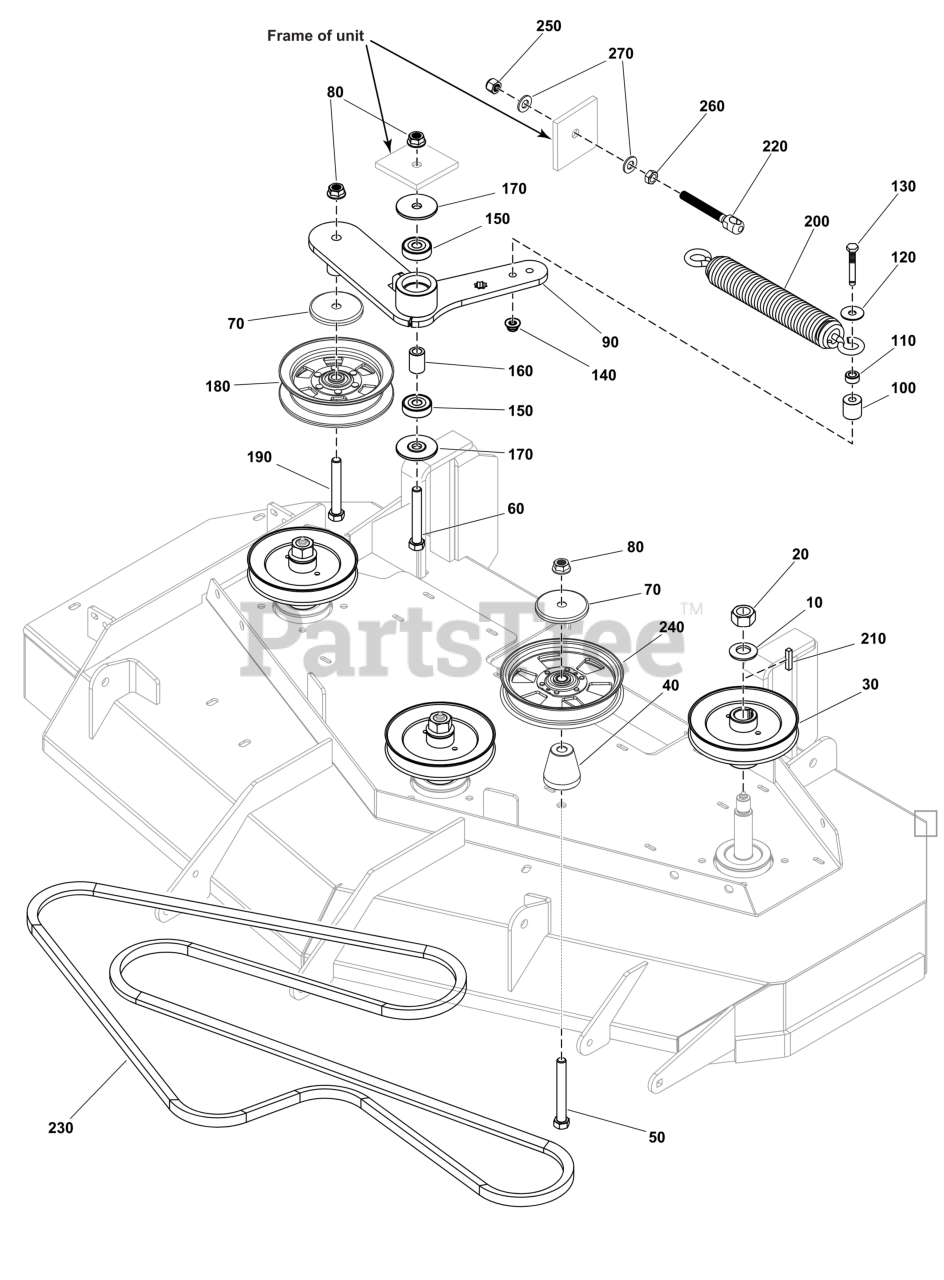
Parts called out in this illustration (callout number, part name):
10	WASHER, Beveled
20	NUT, 3/4-16 HEX
50	BOLT, 1/2-13 X 4-1/2"
60	BOLT, 1/2-13 X 4 GD5
90	ARM, IDLER
110	SPACER, .39 X .75 X .
120	WASHER, 3/8" FENDER
130	BOLT, 3/8-16 X 2-1/4"
140	NUT, 3/8-16 HEX NYLOCK
160	SPACER, .51 X .84 X 1
180	PULLEY, IDLER
190	BOLT, 1/2-13 X 3-1/2"
200	SPRING, Extension
210	KEY, 1/4" SQ X 2.50
220	ANCHOR, SPRING
230	BELT, 5V, 145.40"EL,
250	NUT, 1/2-20 HEX NYLON
260	NUT, 1/2-20 HEX JAM
270	WASHER, 1/2" SAE
